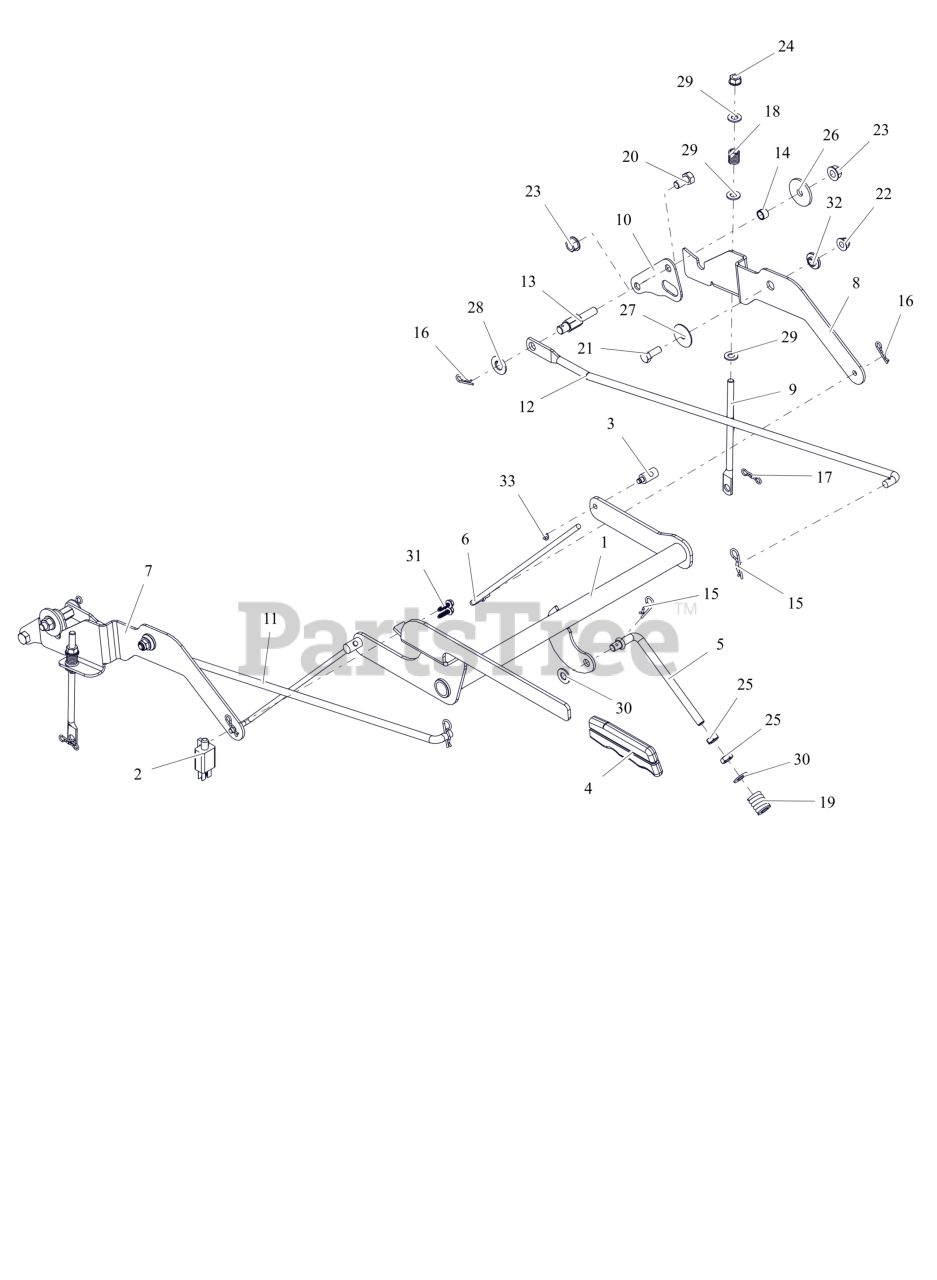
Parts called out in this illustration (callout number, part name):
1	WLDMT, BRAKE LEVER
2	SWITCH- DOUBLE POLE N.O./N.O.
3	TRUNION, 1/4-20
4	GRIP, PARKING BRAKE (GREY)
5	LINK, OVER CENTER, PARKING BRK
6	LINK, BRAKE ARM
7	INTERLOCK, RH BRAKE LINK
8	INTERLOCK, LH BRAKE LINK
9	LINK, BRAKE COG
10	PLATE, TRANSAXLE ADAPTOR
11	LINKAGE, STEERING - RH
12	LINKAGE, STEERING - LH
13	POST, STEERING LINK MOUNTING
14	SPCR, SLV .385X.500X.350
15	PIN, HAIR #203 .09X1.50 ZCC
16	PIN, HAIR #213 .08X1.19 ZCC
17	PIN, BOWTIE #72 ZCC
18	SPRING, COMPRESSION
19	SG-COMP .187X.56X1.62
20	BLT,HEX .38-16X.75 G5 ZCC
21	BLT, HEX .31-18X.875 G5 ZCC
22	NUT,LK-NYL-FLG .31-18 G5ZC120
23	NUT-LK-CTR-FLG .375-16 GF ZCC
24	NUT,LK-CTR-FLG .31-18 GF ZCC
25	NUT-JAM .375-16 G2 ZCC
26	WSHR, FLT .380X1.50X.125 ZCC
27	WSHR, FLT .347X1.254X.048 ZCC
28	WSHR, FLT .505X1.00X.062 ZCC
29	WSHR,FLT .344X.688X.065 ZCC
30	WSHR,FLT .406X.812X.065 ZCC
31	SCR, PLASTITE #12X.75 ZCC
32	BSHG, FLG .325X.499X.26X.88
33	RG-RTNG-EXT .250X.025
